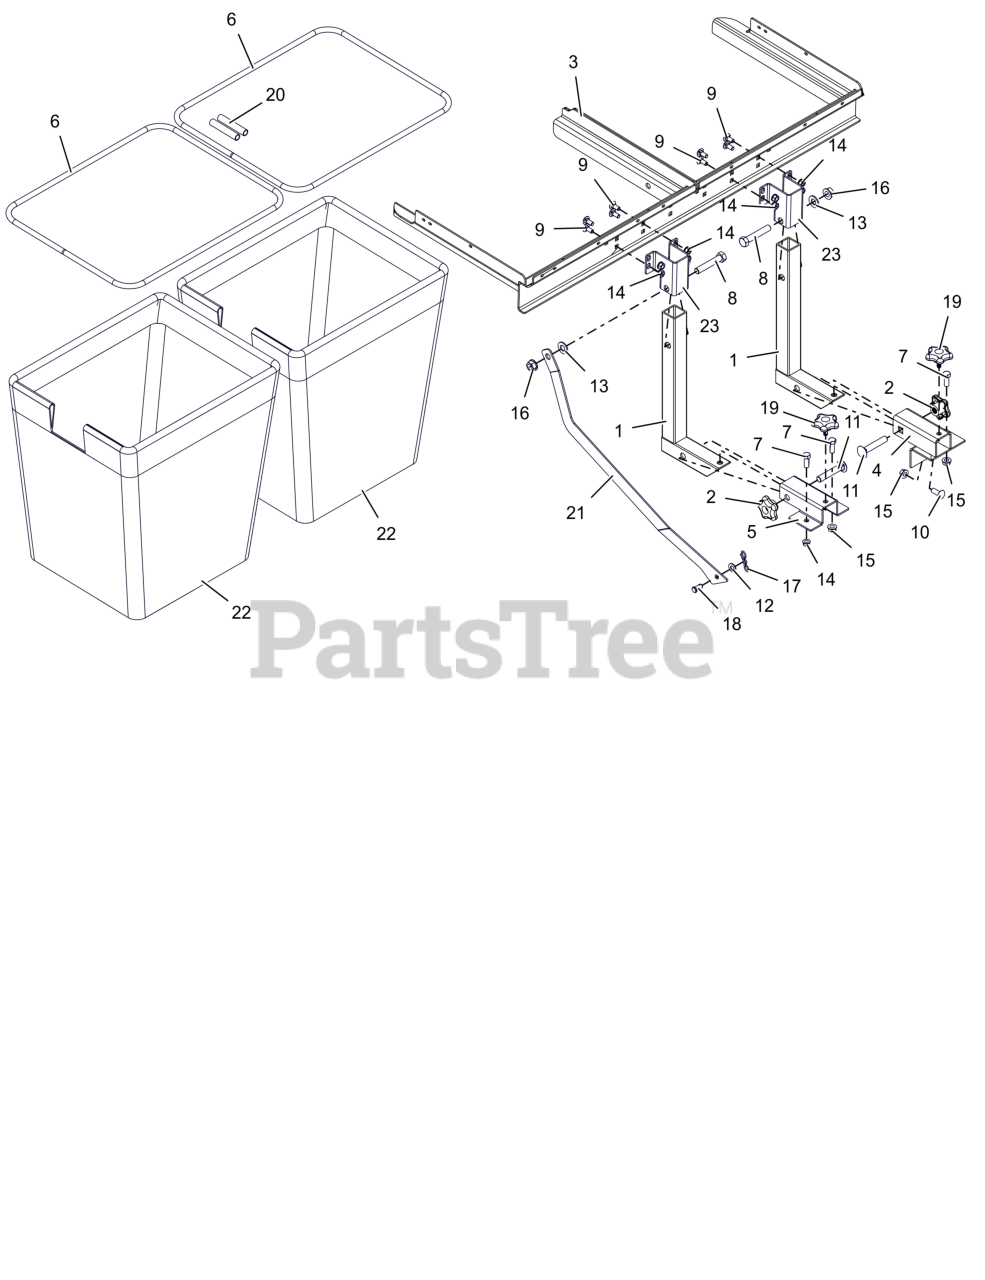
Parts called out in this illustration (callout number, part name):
1	BRKT, RECEIVER SLEEVE INSERT
2	KNOB, WING
3	WLDMT, BAGGER FRAME (BLACK)
4	WLDMT, BAGGER MOUNT, LOWER (BLACK)
5	BRKT, RECEIVER LOWER
6	FRAME, BAG
7	BLT,HEX .38-16X1.00 G5 ZCC
8	BLT, HEX .50-13X2.75 G8 ZCC
9	BLT,RHSN .31-18X.75 G5 ZCC
10	BLT,RHSSN .38-16X1.00 G5 ZCC
11	BLT, RHSN .50-13X2.75 G5 ZCC
12	WSHR,FLT .406X.812X.065 ZCC
13	WSHR,FLT .531X1.062X.095 ZCC
14	NUT,LK-CTR-FLG .31-18 GF ZCC
15	NUT-LK-CTR-FLG .375-16 GF ZCC
16	NUT-LK-CTR-FLG .500-13 GG ZCC
17	PIN, BOWTIE .091X1.875 ZCC
18	PIN-CLEV .38X.75 YWZC
19	KNOB, WING STUDDED
20	HOSE, VINYL
21	BRKT, BAG FRAME SUPPORT BAR (BLACK)
22	BAG- MESH - 19 INCHES LONG
23	BRKT, BAGGER MOUNT, UPPER
